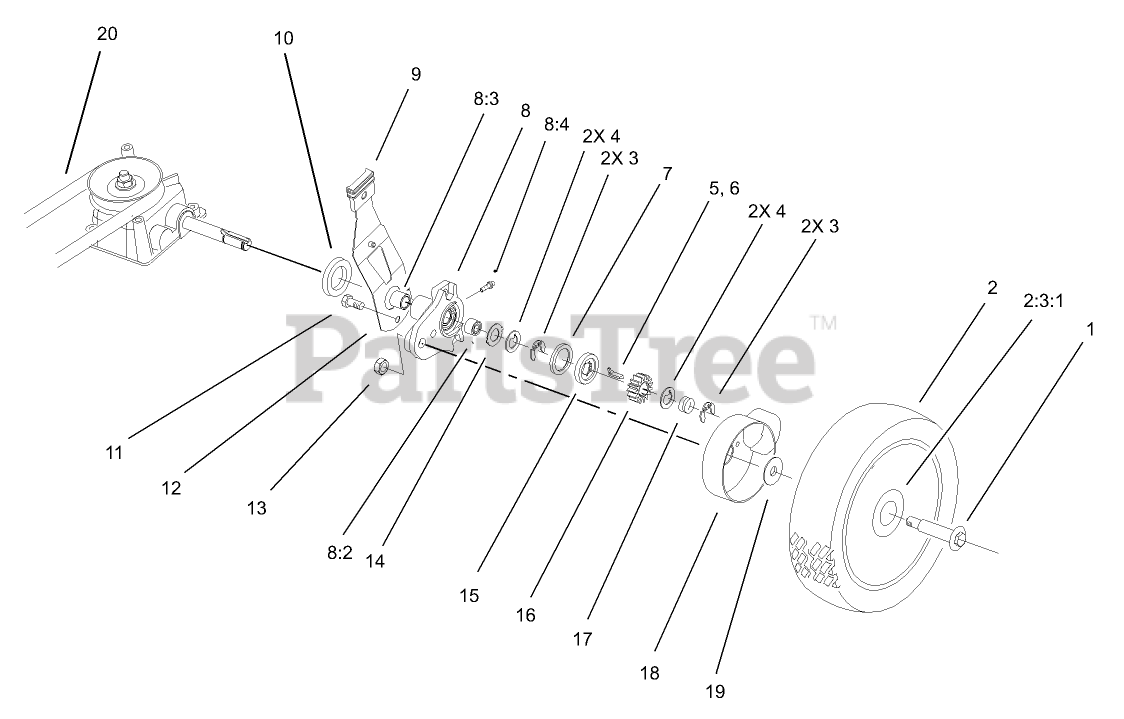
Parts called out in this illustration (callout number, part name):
1	BOLT-SHOULDER
2	WHEEL TIRE ASM (SP)
2:3:1	BUSHING
3	RING-RETAINING,CLIP
4	WASHER-THRUST, KEYED
5	KEY-ROCKING, RH
6	KEY-ROCKING, LH
7	RING-FRICTION
8	PIVOT ARM ASM
8:2	BUSHING
8:3	BUSHING
8:4	FITTING-GREASE
9	KNOB-ARM
10	CAP-END
11	SCREW-HWH
12	SPRING ARM ASM
13	LOCKNUT
14	WASHER-ARM, PIVOT
15	WASHER-CLUTCH
16	GEAR-PINION
17	SPRING-COMPRESSION
18	COVER-WHEEL
19	SPACER-COVER, WHEEL
20	BELT-V
